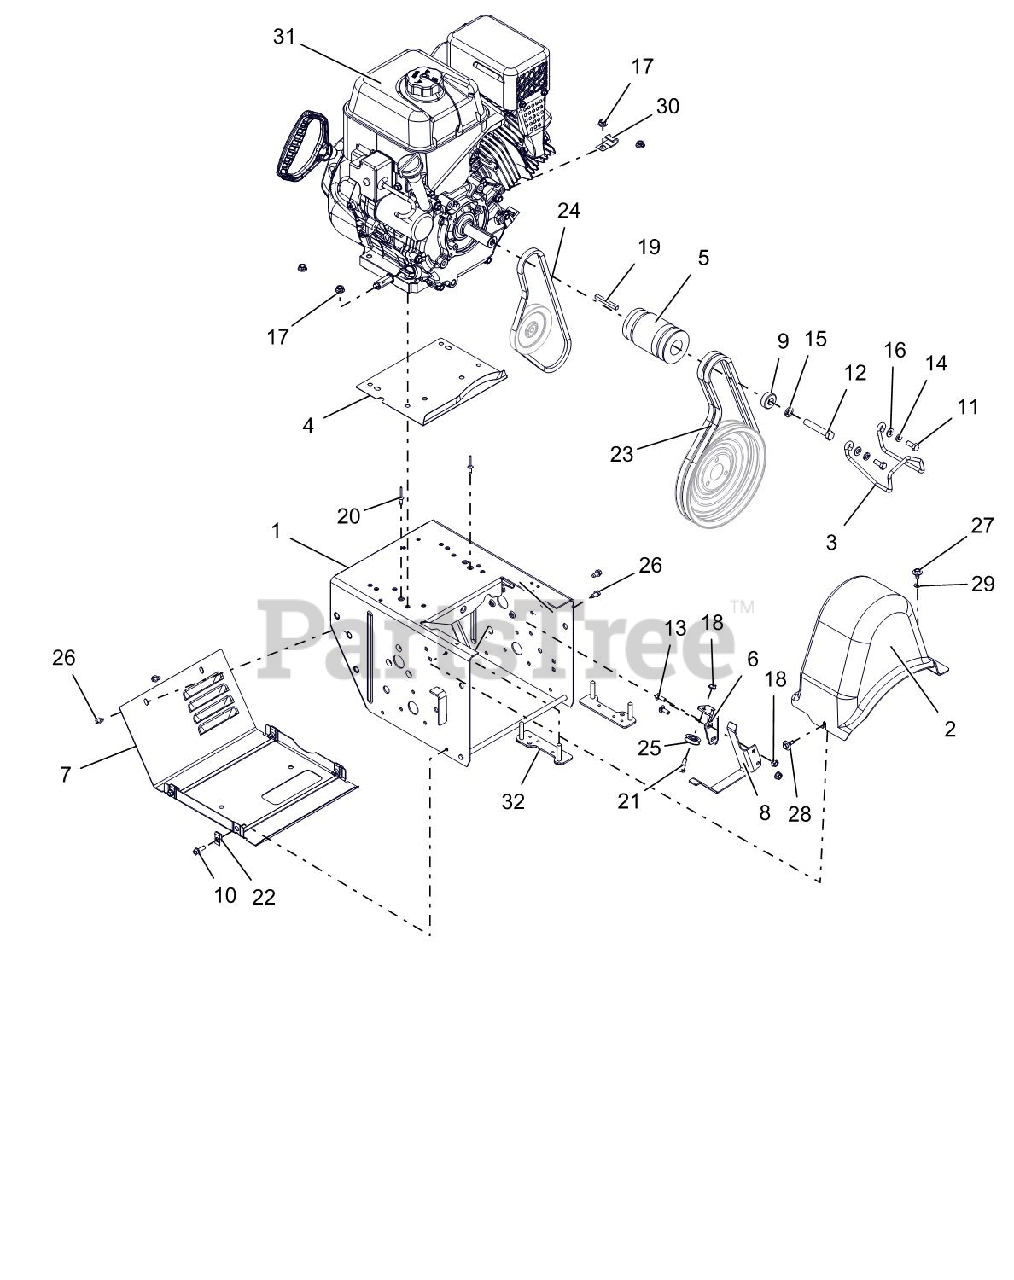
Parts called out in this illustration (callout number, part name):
1	FRAME, MAIN - PRO (WELDMENT)
2	COVER, BELT-LARGE
3	FINGER, BELT
4	BAFFLE, WATER - LARGE BLOCK
5	SHEAVE, COMBO HYDRO WHEEL 4L
6	BRACKET, CLUTCH CABLE
7	COVER, BOTTOM - VENTILATED
8	FINGER, BELT - FLAT
9	BSHG-SPACER .47X1.25X.50
10	BLT-HEX .25-20X.75 HWH YZ GR5
11	BLT-HEX .31-24X.75 YWZC GR5
12	BLT-HEX .44-20X2.50 GR5 YWZC
13	@BLT-RDHDSQNK .25-20X.75 G5YZ
14	WSHR-LK .312X.097 HVY YWZC
15	@WSHR-LK .44X.109 REG YWZC
16	@WSHR-FL-STL.344X.688X.065YWZC
17	@NUT-LK-CTR-FLG .31-18 YZ GR F
18	@NUT-LK-TOP-FLG .25-20 YWZC
19	KEY .25X.25X2.25
20	RVT-POP .187 YZ
21	BOLT, SHLDR-.375X.375X.25-20
22	NUT-RTNR .25-20X.56
23	V-BELT, HA-RAW EDGE (SET)
24	V-BELT, 4L-WRAPPED
25	PULLEY, CABLE
26	SCR-TAP .25-20X.50 HWH TR YWZ
27	SCR-TAP .25-20X.50 LGHWH TR YZ
28	SCR-TAP .25-20X.5 CAPTIVE
29	NUT-PUSH .25X.50 O.D.
30	J-CLAMP
31	ENGINE, ARIENS AX414 240V/60W
32	STRAP, BOLT-LARGE
